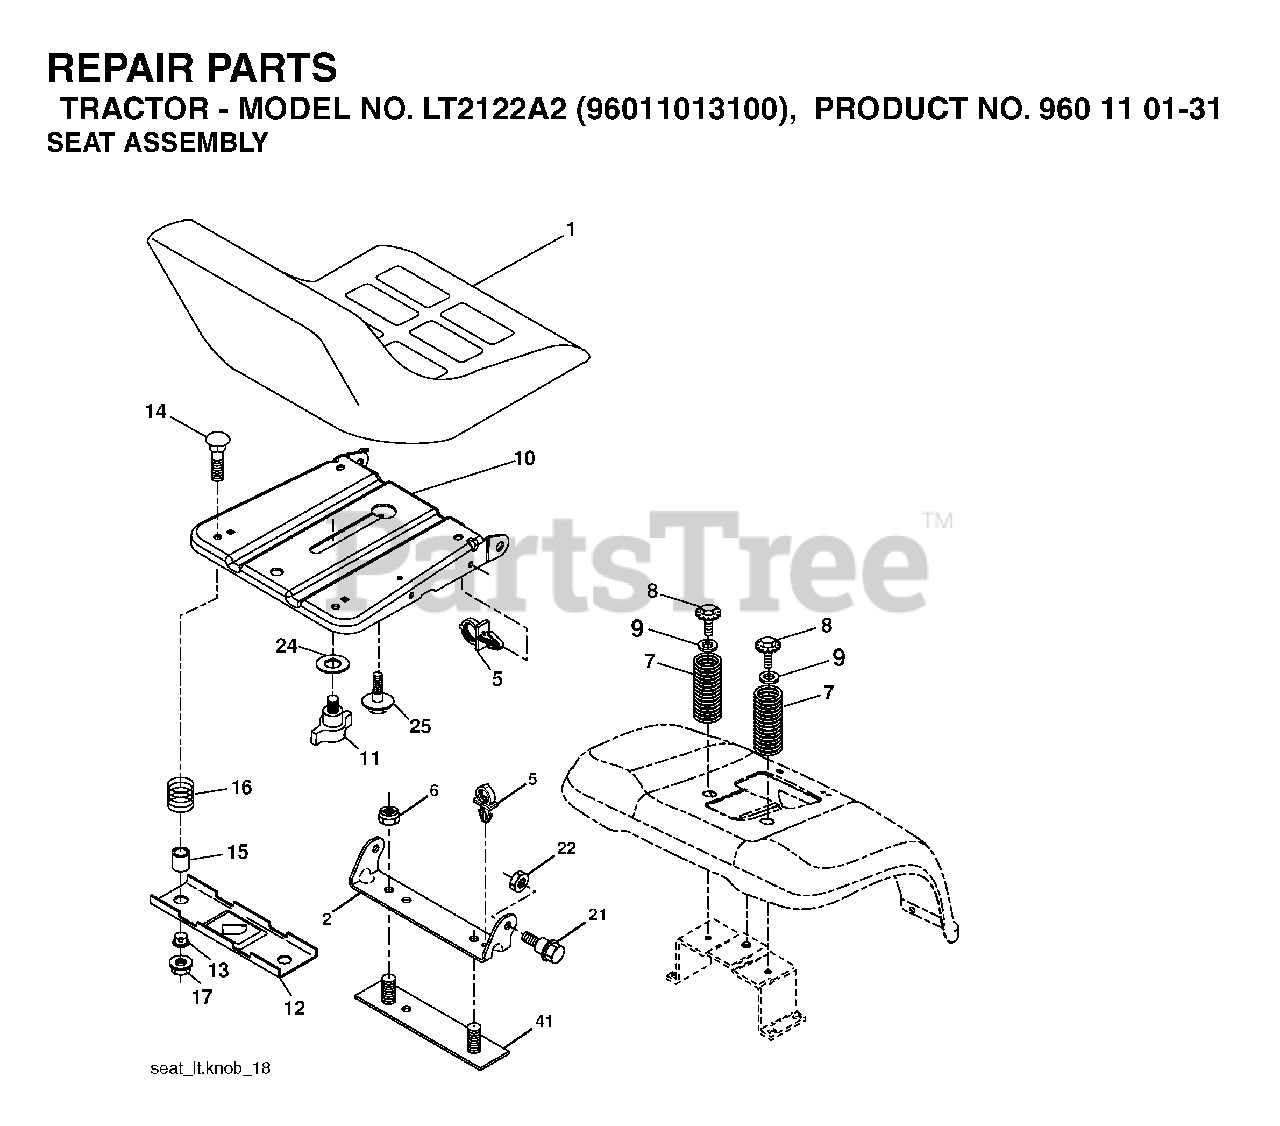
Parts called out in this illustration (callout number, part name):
1	SEAT.XG150.BLK.KB/SLD.NO-LOGO
2	SEAT PIVOT BRKT
5	PUSH CLIP
6	NUT
7	SPRING COMPRESSION
8	SCREW 3/8-16X1
9	WASHER
10	PAN.ASM.SEAT.1SLOT
11	KNOB.SEAT.ADJ.WINGNUT
12	BRKT.MNTNG.SWITCH.SEAT
14	BOLT.ROUND.HEAD.SQUARE.NECK
15	SPACER SPLIT
16	SPRING COMPRESSED
17	NUT T
21	BOLT.SHOULDER.5/16-18
22	NUT.71038.31-18.HEX.NYLOCK
25	BOLT,SHOULD
